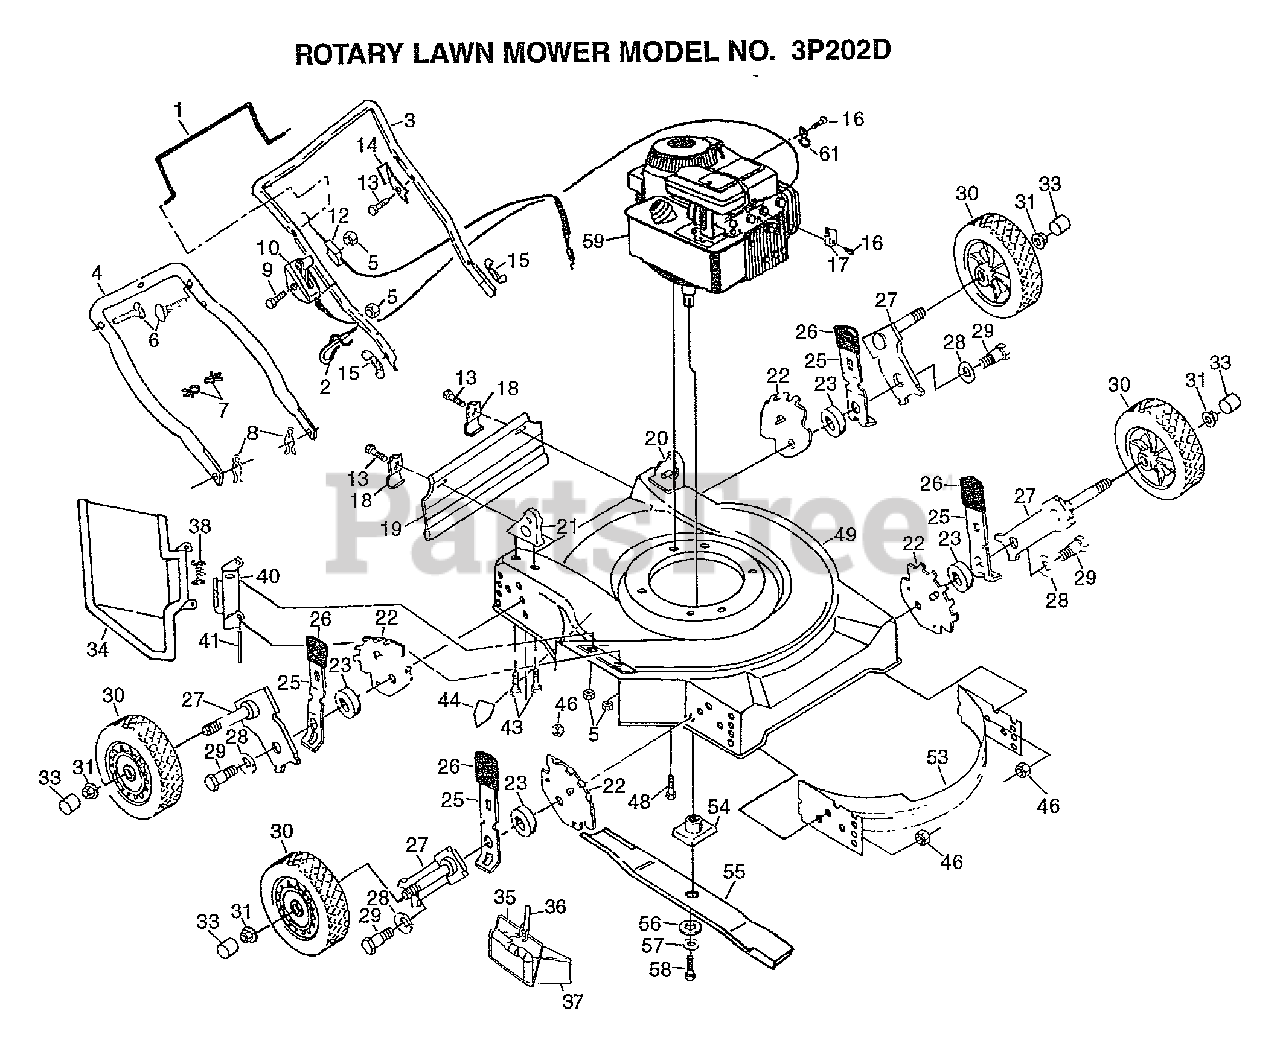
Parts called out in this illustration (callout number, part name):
1	CONTROL BAR PM
2	ROPE GUIDE
6	BOLT.HANDLE.LM
8	HAIRPIN COTTER
9	SCREW.HXHD.WASH.
10	CONTROL THROTTLE
12	"CABLE,ENG ZONE CO"
13	TAPPING SCREW
14	"BRKT,UPSTOP"
15	"NUT,WING PM"
16	SCREW PM
17	CABLE CLAMP
18	"BRKT,DEFL PM"
19	SKIRT.REAR.FGD.22
20	HDLE BRKT ASSY LH
21	HDLE BRKT ASSY.RH
22	BRACKET.ADJ.9POS.
23	SPACER.HEIGHT.ADJ
25	SPRING SELECTOR
26	KNOB PM
27	ARM.AXLE.ASM.BZP.
28	"WASHER, BELLEVIL."
29	BOLT SHLD 3/8-16
30	WHEEL.ASM
31	HEX FLANGE LOCKNT
33	HUB CAP-PLASTIC
34	GUARD.DISCH.22SD.
35	MULCHER BAIL
36	LATCH.BAIL.MULCH.
37	MULCHER PLUG
38	SPRING.HINGE
40	BRACKET.HINGE.W/F
41	ROD.HINGE.COMBI-C
43	SCREW 5/16-18X3/4
44	DECAL HYT
46	LOCKNUT PM
48	BOLT.ENG.3/8-16
49	KIT HOUSING MOWER
53	BAFFLE.FRT/REAR
54	BLADE ADAPTOR
55	"BLADE.MULCH.22"""
56	"WASHER,HARDEN"
57	LOCKWASHER
58	SCREW
61	GUIDE CLIP PM
